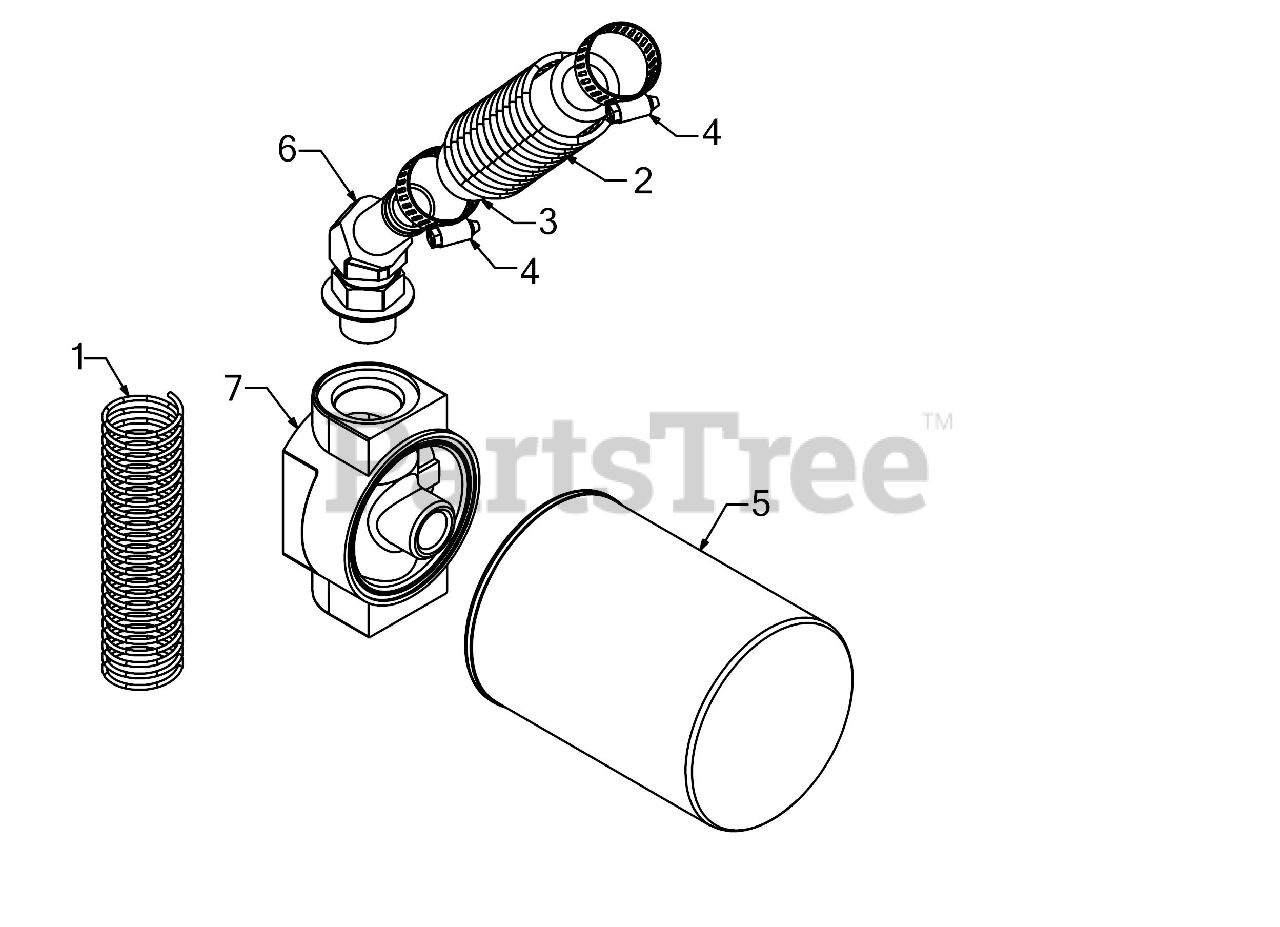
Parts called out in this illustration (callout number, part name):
1	HOSE GUARD
2	HOSE GUARD
3	RETURN HOSE
4	HOSE CLAMP-5/8
5	OIL FILTER
6	HYDRAULIC FITTING1 1/16 ORB x .75
7	FILTER HOUSING
